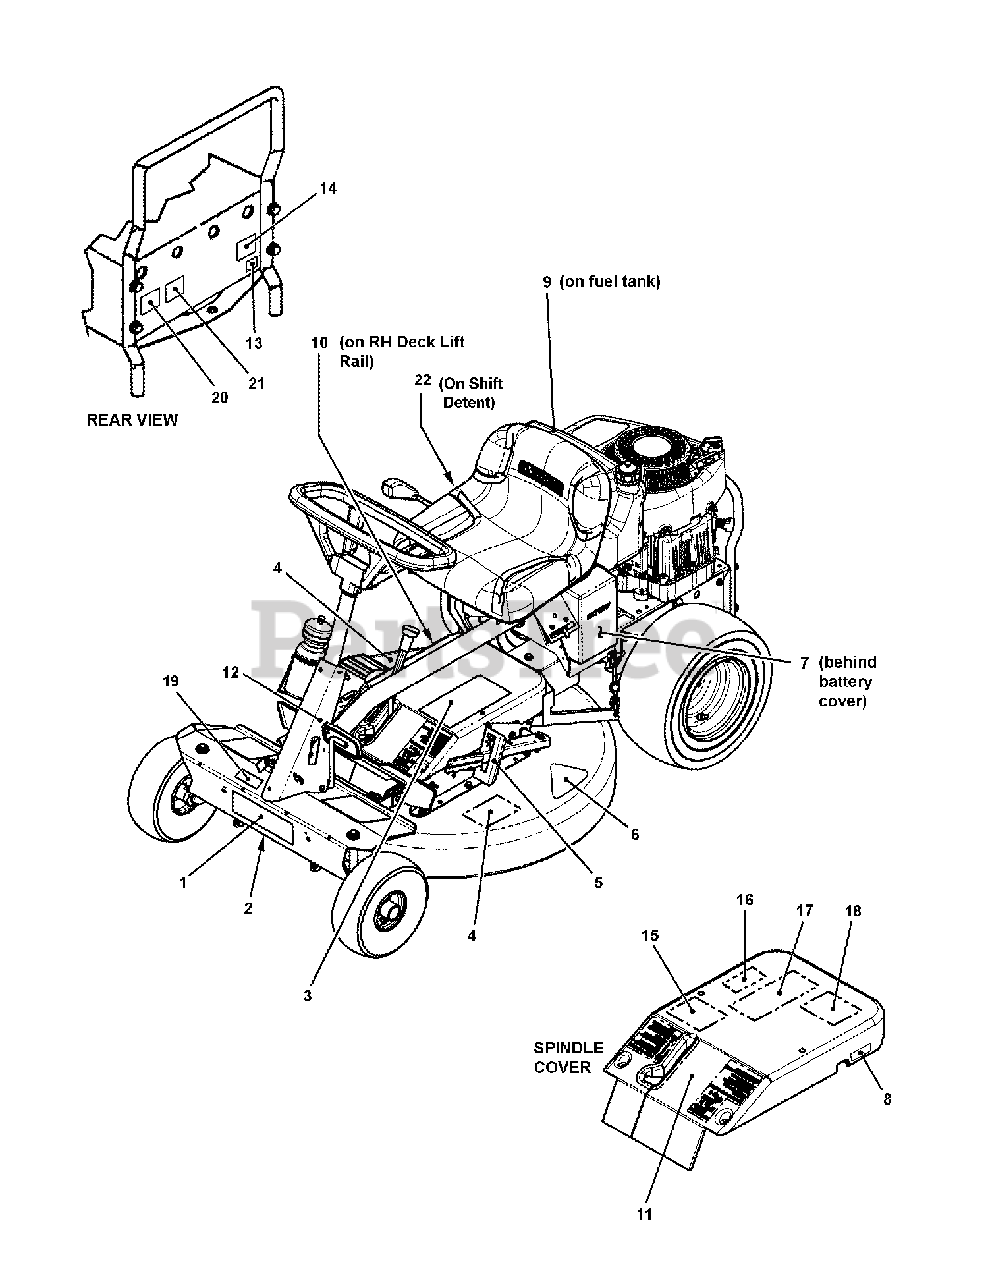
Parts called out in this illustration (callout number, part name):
1	DECAL, SNAPPER/w Turtle
2	DECAL, Battery Storage
3	DECAL, Safety Instructions (Spanish/Italian)
3	DECAL, Safety Instructions (English/Dutch)
3	DECAL, Safety Instructions (French/German)
3	DECAL, 8-Panel Symbols, Euro RER (replaces items 7029113, 7029114, 7073199, 7073200, 7029345, 7029346, 7101166 & 7103905)
4	DECAL, Deck Symbols- International
5	DECAL, Height of Cut
6	DECAL, 25 Inch (Hi-Vac)
6	DECAL, 64cm (25 Inch) (Hi-Vac)
6	DECAL, 28 Inch (Hi-Vac)
6	DECAL, 72cm (28 Inch) (Hi-Vac)
7	DECAL, Battery Caution, Multi-Language
7	DECAL, Battery Orientation, Euro RER
8	DECAL, Remove Battery, Symbols, Euro
9	DECAL, Caution, Fuel Leakage (English)
9	DECAL, Caution, Fuel Leakage (Dutch)
9	DECAL, Caution, Fuel Leakage (Italian)
9	DECAL, Caution, Fuel Leakage (Spanish)
9	DECAL, Caution, Fuel Leakage (French)
9	DECAL, Caution, Fuel Leakage (German)
9	DECAL, Caution, Fuel Leakage
10	DECAL, Deflector, French/German
10	DECAL, Deflector Caution (English/Dutch)
10	DECAL, Blade Caution, Euro RER
11	DECAL, Brake Operation (Italian)
11	DECAL, Brake Operation (Spanish)
11	DECAL, Brake Operation (German)
11	DECAL, Brake Operation (French)
11	DECAL, Brake Operation (Dutch)
12	DECAL, Clutch Brake
13	DECAL, Euro Community (CE)
14	DECAL, European Noise Control (98 dB)
14	DECAL, European Noise Control (100 dB)
15	DECAL, No Mow in Reverse (Euro)
16	DECAL, Deck/Chute International Warning
17	DECAL, Service Parts, Euro
18	DECAL, ISO (EURO) No Mow In Reverse
19	DECAL, ID, Parking Lock
20	DECAL, ID Tag, Model/Serial # (Not a Sellable Item)
21	LABEL, Equip. Soley for Export, Exempt
22	DECAL, Reverse Lockout
